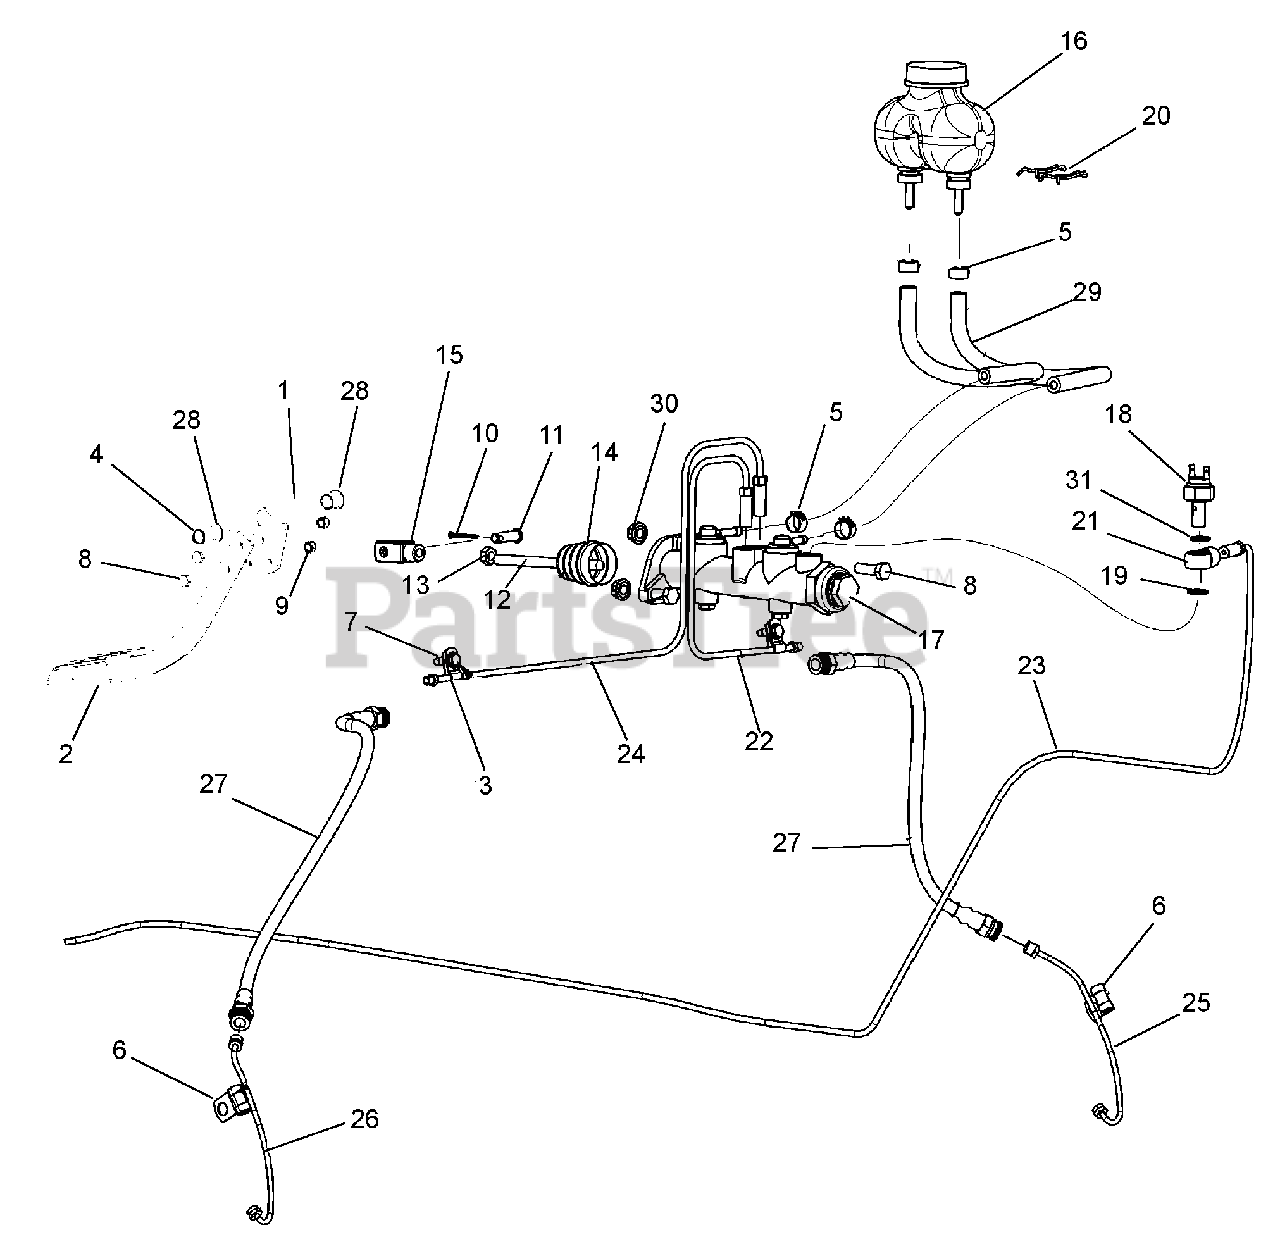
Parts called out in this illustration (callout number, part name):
1	BRAKE PEDAL PIVOT WELDMENT
2	BRAKE PEDAL ASSEMBLY
3	WIRING/TUBE CLIP FOR 1/4 OD
4	SNAP RING, .625 X .035 EXT
5	CLAMP, FUEL LINE
6	HOSE CLAMP 1/4 ID
7	HH DRILL SCREW 1/4 X 3/4 LG
8	BOLT, HEX 5/16-18 X 1 GR5 YELLOW ZINC
9	NUT, HEX NYLOCK .312-18
10	PIN, COTTER .09 X 1
11	PIN, CLEVIS 5/16 X 1
12	MASTER CYLINDER PUSH ROD
13	NUT, JAM M8-1.25 TWZC
14	MASTER CYLINDER BOOT
15	MASTER CYLINDER CLEVIS
16	DUAL RESERVOIR BRAKE FLUID WITH CAP
17	DUAL MASTER CYLINDER
18	BRAKE SWITCH, HIGH PRESSURE
19	WASHER, COPPER 3.5 MM
20	MASTER CYLINDER RESERVOIR CLIP
21	BULK HEAD FLOW THROUGH
22	FRONT BRAKE LINE LEFT HAND
23	ST STEEL BRAKE LINE
24	FRONT BRAKE LINE 21 1/4 RIGHT HAND ST
25	FRONT BRAKE LINE END LEFT HAND STEEL
26	FRONT BRAKE LINE END RIGHT HAND STEEL
27	BRAKE LINE RBR 17" M10 X 1 FEMALE
28	BUSHING 3/4 OD X 5/8 ID X 3/4 FLG HD
29	12.5" FUEL LINE/HYDRAULIC FLUID RESVOIR.
30	NUT, TOP LOCK FLANGE .31-18
31	MASTER, CYLINDER CPPR WASHER 16 X 10 X 1.5 MM
